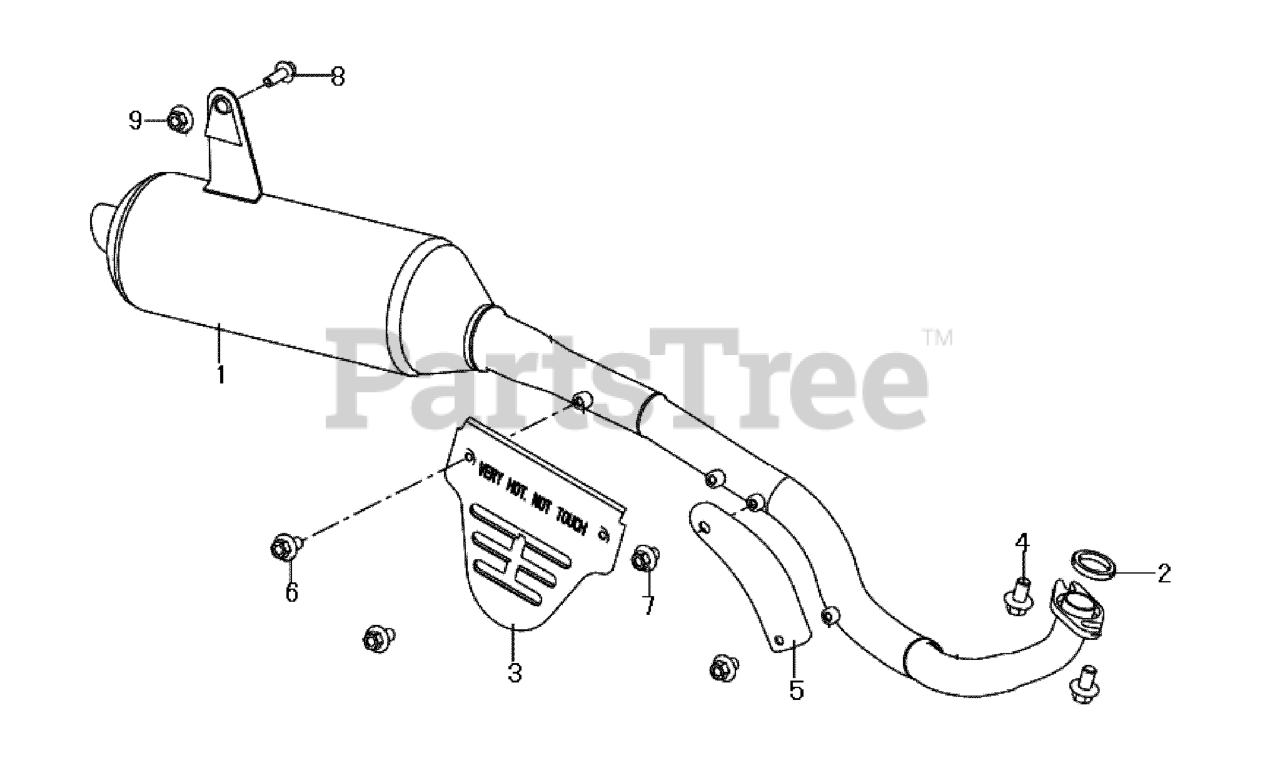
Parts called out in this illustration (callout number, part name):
1	MUFFLER ASSY.
2	GASKET, EXHAUST
3	GUARD, EXHAUST
